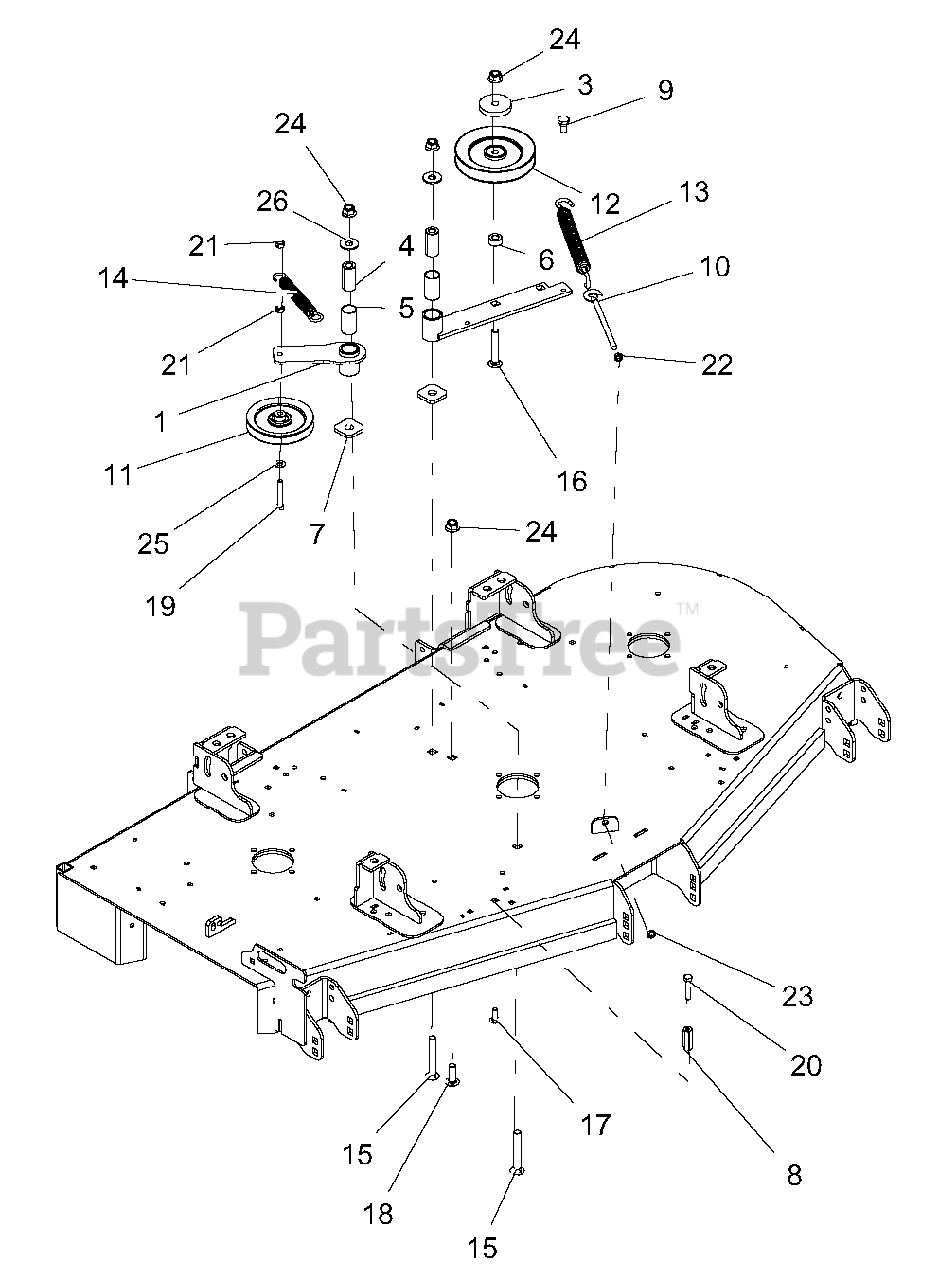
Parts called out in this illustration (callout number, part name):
1	WMT, IDLER PIVOT ARM-BLACK
3	CAP, IDLER BEARING SEALING
4	BSHG, SPCR .502X.997X2.03
5	BSHG, 1.00X1.125X1.937
6	BSHG, SPCR .502 X .997.50 PM
7	WSHR, -FLT.640X1.75X.250
8	NUT-HEX COUPLING
9	BLT, SHLDR EP .38-16X.30 HEX YZ
10	BOLT, .38-16X6.00 .62 DIA EYE
11	IDLER, V-5.00" W/.69 STANDOFF
12	SHEAVE, .50" ID X 6.00" OD V-IDLER
13	SPRG, EXTENSION
14	SPRG, EXTENSION
15	@BLT-RDHDSQNK .50-13X3.50 G5 Y
16	@BLT-RDHDSQNK .50-13X3.00 G5 Y
17	@BLT-RDHDSHSQNK.38-16X1.0 G5YZ
18	BLT-RDHDSQSHNK .50-13X1.50 YWZC
19	BLT-HEX .38-16X2.25 GR5 YWZC
20	BLT-HEX .38-16X1.75 GR5 YWZC
21	@NUT-LK-CTR .38-16 YWZC
22	NUT, JAM .375-16 YWZC
23	@NUT-LK-CTR-JAM .375-16 YWZC
24	NUT-LK-NYL-FLG .50-13 YWZC
25	@WSHR-FL-STL.406X.812X.065 YWZ
26	@WSHR-FL-STL.563X1.38X.109YWZC
